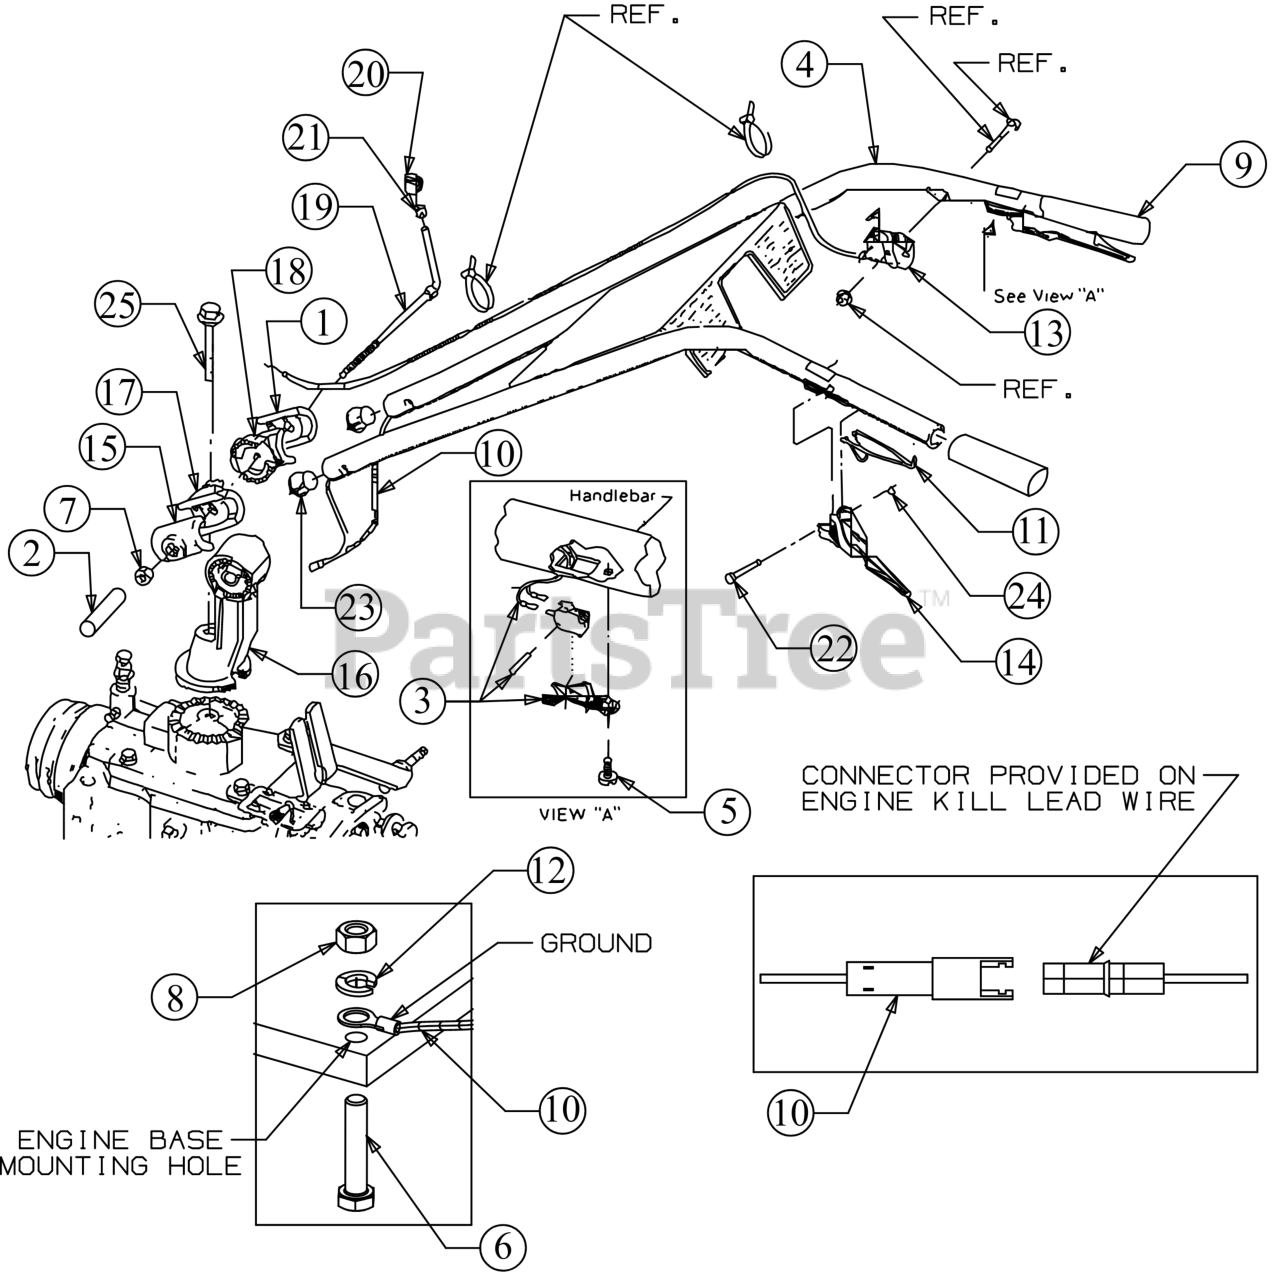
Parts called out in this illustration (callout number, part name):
1	CLAMP (RH) HORSE
2	CAP:PLUG HI TEMP
3	MICRO SWITCH ASSEMBLY
3	MICRO SWITCH
4	HANDLE ASSEMBLY
5	SCREW #10-16 X .500
6	SCREW 5/16-18 X 1.5 LG
7	HEX NUT
8	HEX NUT
9	GRIP 1.188 X 4.562
10	ENGINE HARNESS
12	LOCK WASHER 5/16
13	THROTTLE CABLE ASSEMBLY
15	CLAMP (LH) HORSE
16	HANDLE BAR BAS
17	RATCHET (LH) RED
18	RATCHET (RH) RED
19	STUD-H/BAR W/NUT
20	CONTROL KNOB
21	RING-TOLERANCE
22	PIN-PIVOT
23	RETAINER-HARNESS
24	RING-KLIP
25	BOLT 132-13X3.5 FH
